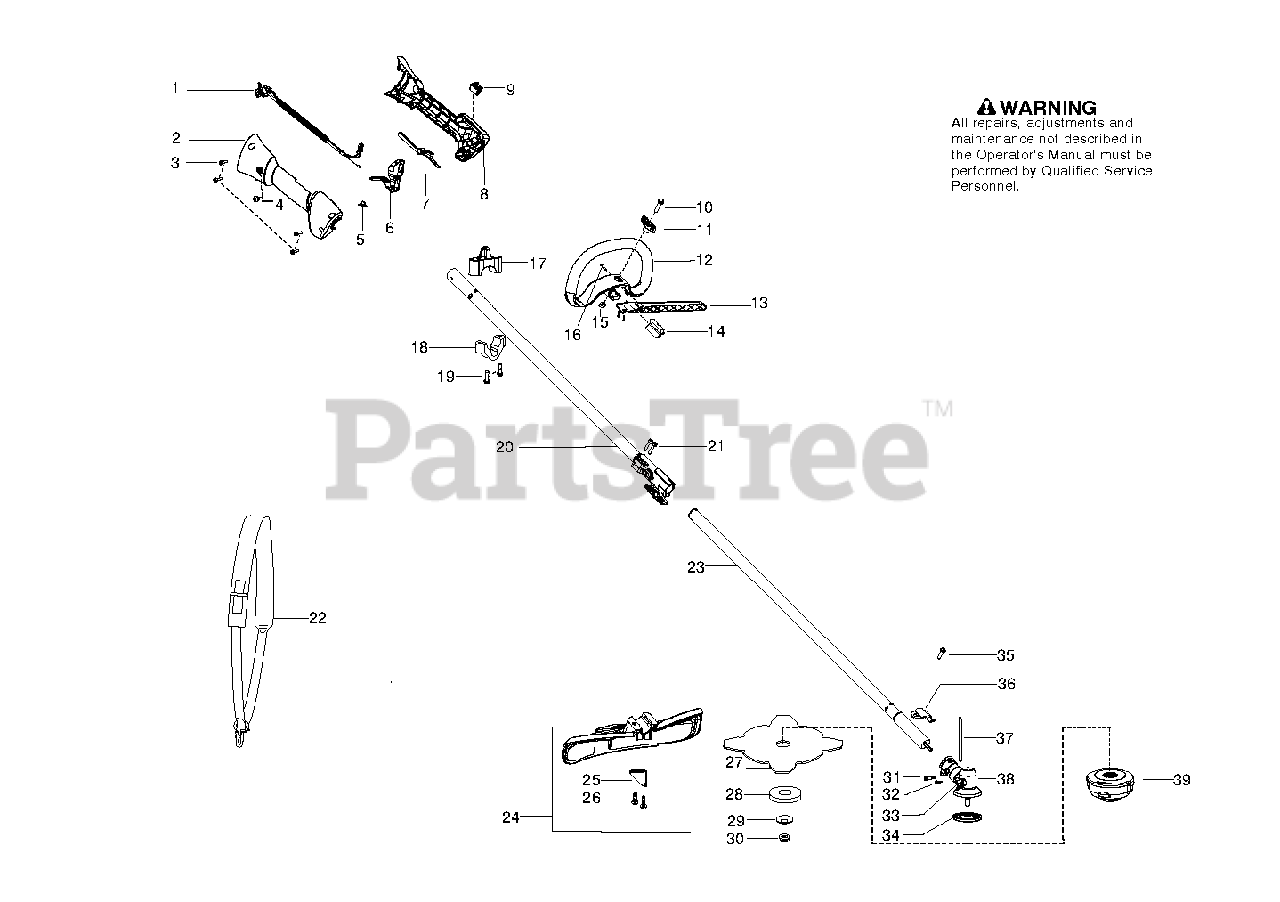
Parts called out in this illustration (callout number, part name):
1	ASSY CABLE / WIRE HARNESS
2	HSG THROTTLE RIGHT HVA
3	SCREW M4 X 1.75 PT 16MM
4	SCREW-10-14 X 1/2 PLASTITE
5	SPRING TRIGGER
6	TRIGGER THROTTLE HVA ORANGE
7	THROTTLE LOCKOUT HVA ORANGE
8	HSG THROTTLE LEFT HVA
9	SWITCH
10	SCREW M6X50
12	HANDLE LOOP
14	SPACER PLASTIC
16	SCREW IHSCFTO
17	CLAMP HARNESS UPPER
18	CLAMP HARNESS LOWER
20	DRIVESHAFT
22	Shoulder Strap with Sign
23	KIT LOWER SHAFT
24	KIT COBI SHIELD
25	LINE LIMITER
27	Blade, 8" 4 Tooth (20mm and 1")
28	SUPPORTING CUP
29	SUPPORT FLANGE
30	GEARHEAD NUT - BRUSHCUTTER
31	SCREW - CARB. ADAPTOR
33	PLUG GREASE 9MM
34	DRIVE DISC
35	SCREW 1/4-20 X 7/8 (TAP
36	BRACKET SHIELD STRAIGHT SHAFT
37	LOCKING PIN
38	ASSY GEARBOX
39	Trimmer Head, T25 10mm LH
